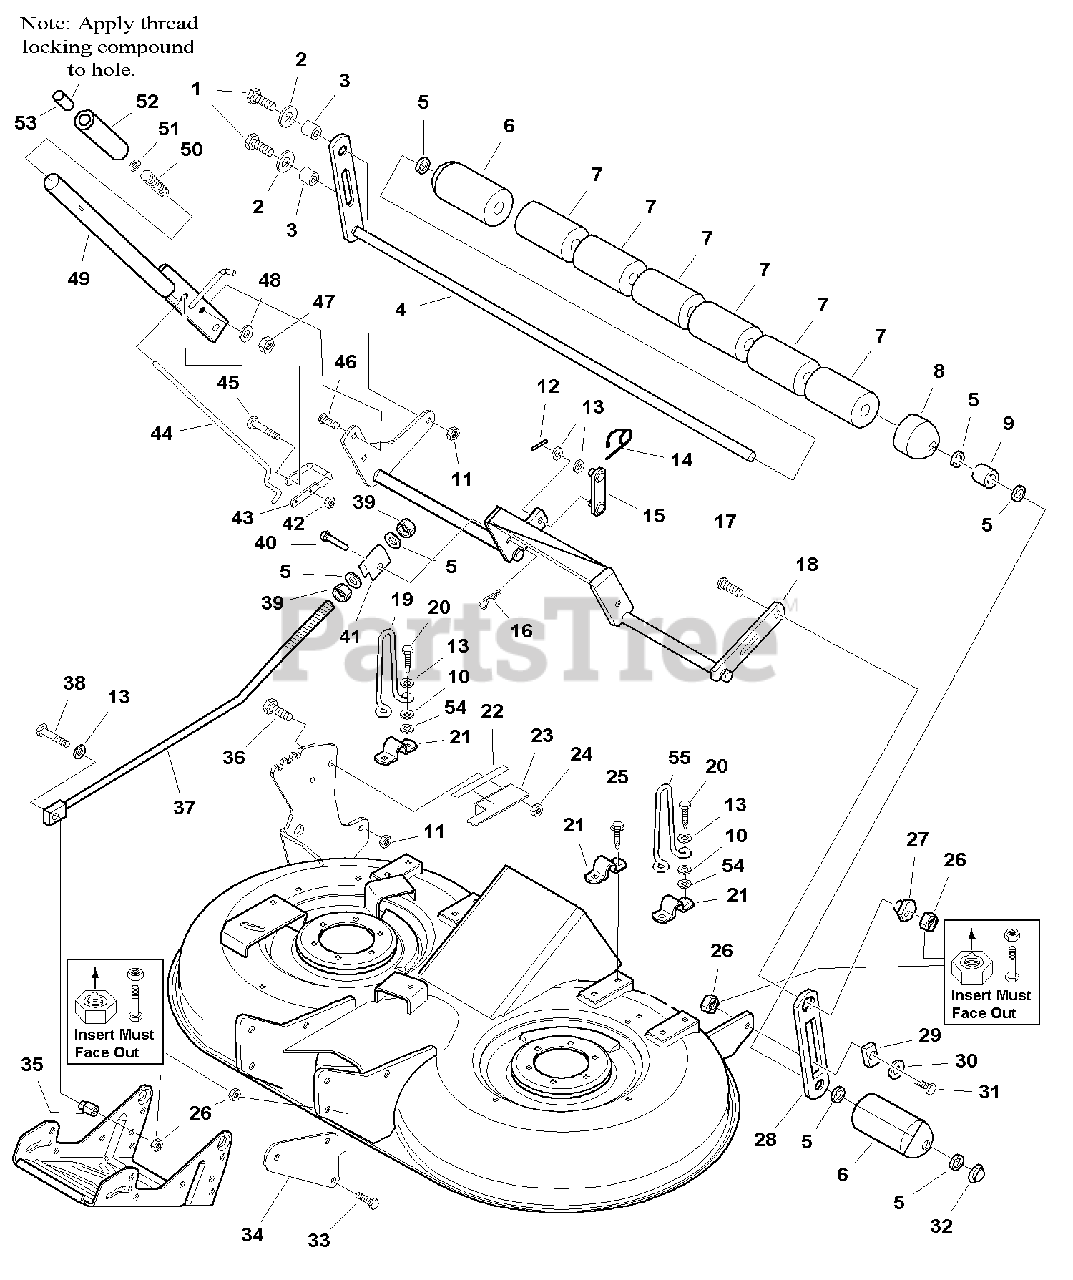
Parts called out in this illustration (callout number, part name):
1	CAPSCREW, Hex Head, 5/16-18 x 1-1/4
4	SHAFT & BAR ASSEMBLY
5	WASHER, 5/8
9	SPACER, .66 ID
10	WASHER
11	NUT, Hex Flange Lock, 5/16-18
12	PIN, Cotter
13	WASHER
14	RETAINER, Pin
15	LINK & PIN ASSEMBLY
16	PIN, Retaining
17	CARRIAGE BOLT, 3/8-16 x 1-1/2
18	SHAFT & ARM ASSEMBLY
20	CAPSCREW, Hex Head Taptite, 5/16-18 x 1-1/4
21	STRAP
22	DECAL, Height of cut
23	BRACKET, Height of Cut
24	NUT, Hex ESNA, 3/8-16
25	CAPSCREW, Hex Head Taptite, 5/16-18 x 3/4
26	NUT, Hex Lock Aluminum Insert, 3/8-16
27	NUT, Hex Adjusting, .99 DIA .687
30	WASHER
31	BOLT, Shoulder, 3/8-16 X 1.34
32	NUT, Push
33	CAPSCREW, Hex Head Whiz Lock, 3/8-16 x 1
34	SUPPORT, Hitch
36	CAPSCREW, Hex Head, 5/16-18 x 3/4
38	CAPSCREW, Hex Head, 3/8-16 x 1-3/4
39	NUT, Hex, 5/8-11
40	PIN, Round Head Drilled, 3/8 x 2
41	TRUNNION
42	NUT, Hex Lock ESNA, 1/4-20
45	CAPSCREW, Hex Head 1/4-20 x 2-1/4
46	CARRIAGE BOLT, 5/16-18 x 1
47	NUT, Hex, 5/16-18
48	LOCKWASHER, 5/16
49	HANDLE ASSEMBLY, Lift
50	SPRING, Compression
51	NUT, Push
52	GRIP, Black
53	BUTTON, Red
54	NUT, Push
